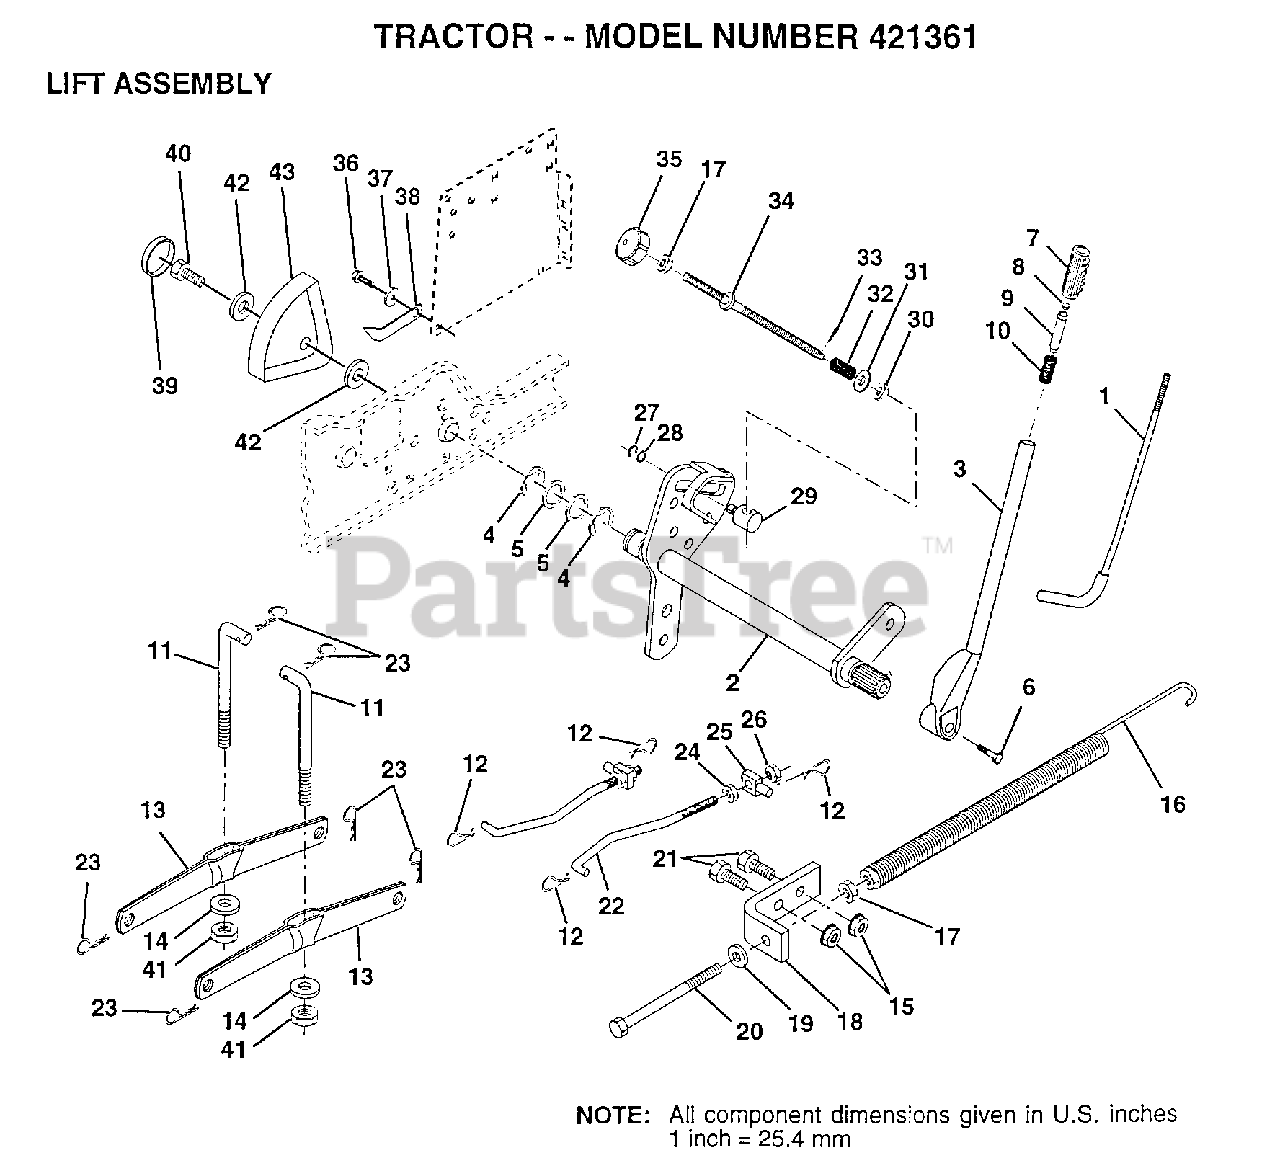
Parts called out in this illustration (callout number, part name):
1	LEVER ROD LT
2	SHAFT.LIFT.VGT.95
4	E-RING
5	WASHER
6	"BOLT,HEX"
7	GRIP HANDLE
10	SPRING T
11	LINK.LIFT.MWR.VGT
12	RETAINER.SPRING
13	ARM SUSP REAR
14	BEARING PVT LH
17	NUT
18	BRACKET SPRING AS
19	WASHER
20	BOLT-ADJ SPRING T
21	BOLT
22	LINK.FRONT
24	NUT
25	TRUNION
26	NUT.LK.W/WSH.1/2.
27	KLIP RING
28	WASHER
29	TRUNION LT
30	NUT T
31	WASHER
32	SPRING.COMP.INF.H
34	ROD.ADJ.LIFT
35	KNOB INF 3/8-16
36	SCREW
37	WASHER T
38	POINTER HGT IND
39	"PLUG,HOLE"
40	SCREW
41	NUT.CROWNLOCK.3/8
42	WASHER
43	HEIGHT INDICATOR
